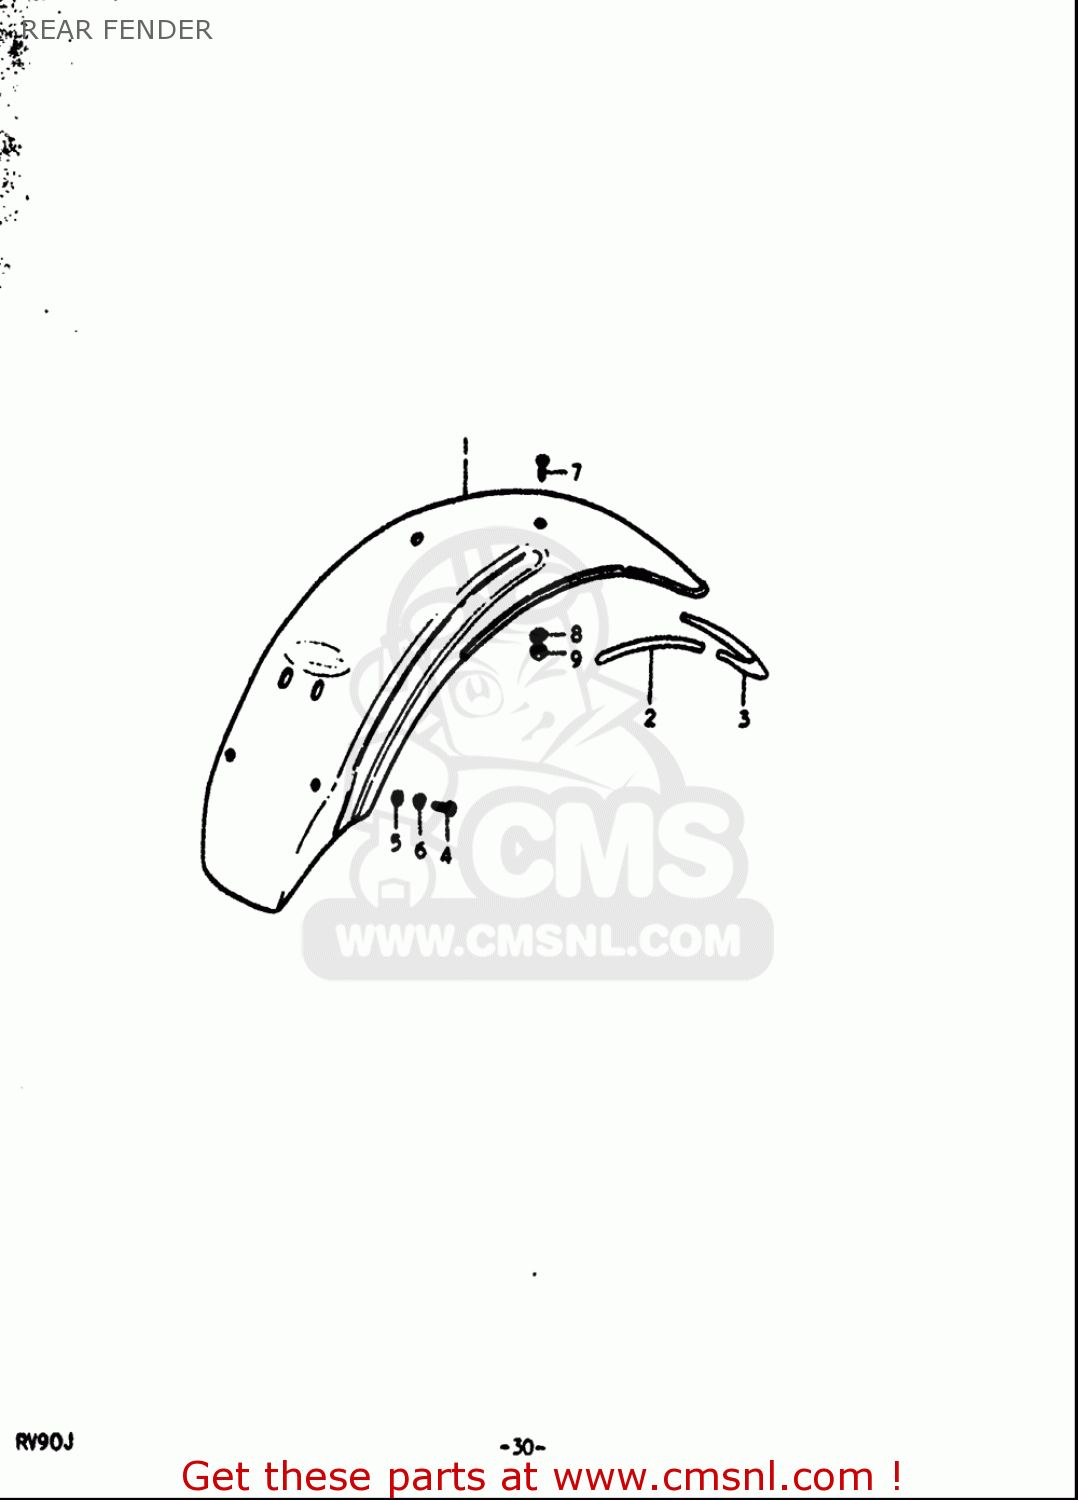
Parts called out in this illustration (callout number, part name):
4	BOLT
5	WASHER
6	WASHER,LOCK
7	BOLT
8	WASHER,LOCK
9	NUT
